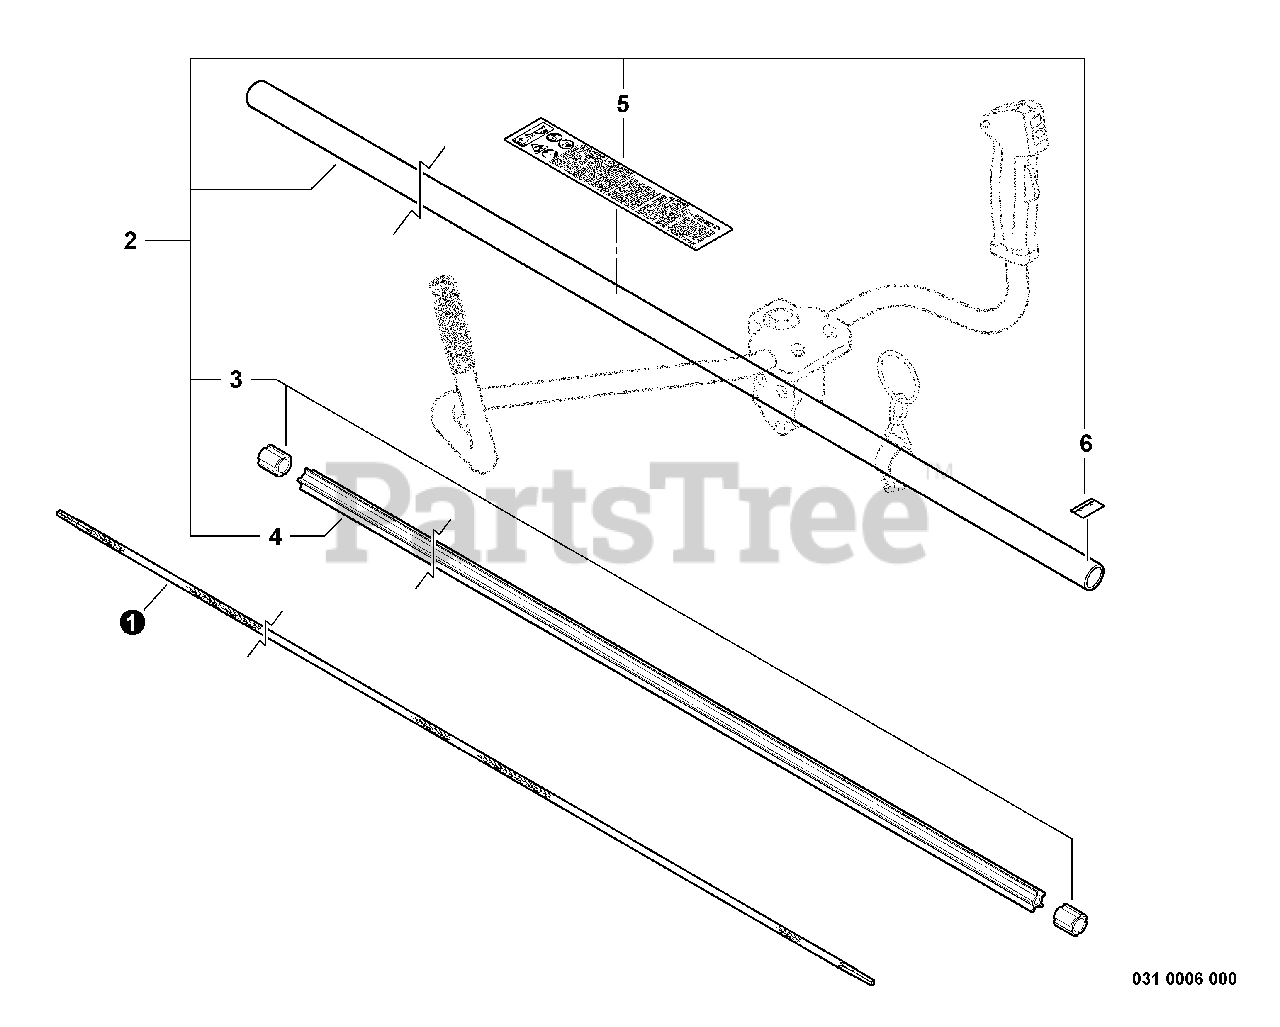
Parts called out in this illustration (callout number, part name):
1	DRIVESHAFT - FLEXIBLE L= 1522
2	MAIN PIPE ASSY
4	LINER, FLEXIBLE 21.6×1420
5	LABEL, CAUTION
6	LABEL - ALIGNMENT
